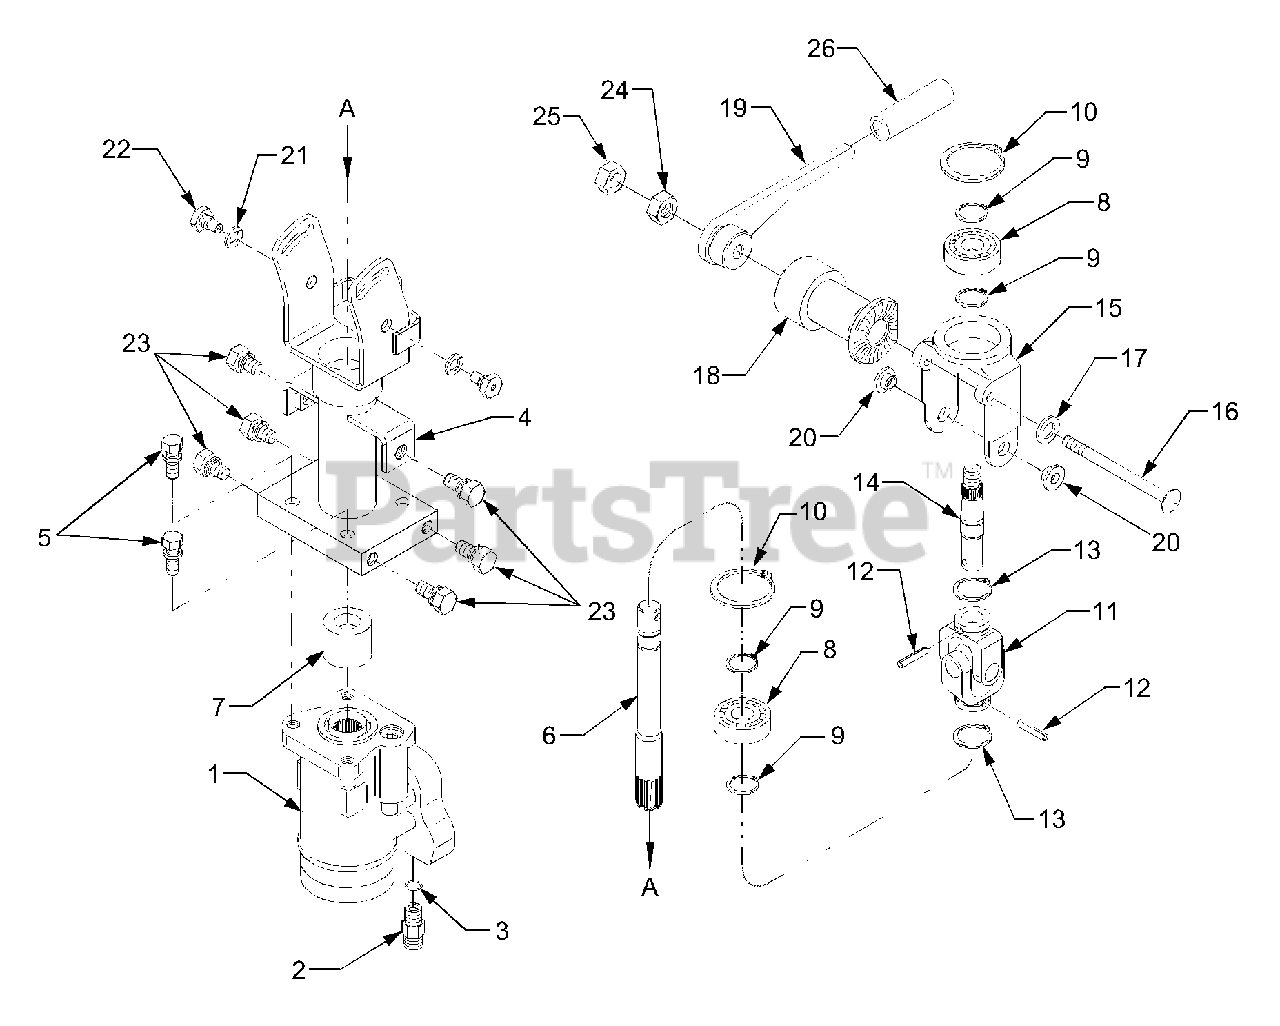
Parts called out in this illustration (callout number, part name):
1	Unit, Power Steering
6	Shaft, Steering
8	Bearing, Ball
9	Cir-clip, External
10	Cir-clip, Internal
11	Joint, Universal
13	Cir-clip, External
14	Shaft, Connecting
17	Washer 1, Holding
18	Washer 2, Holding
21	Washer, Spring
26	Grip
